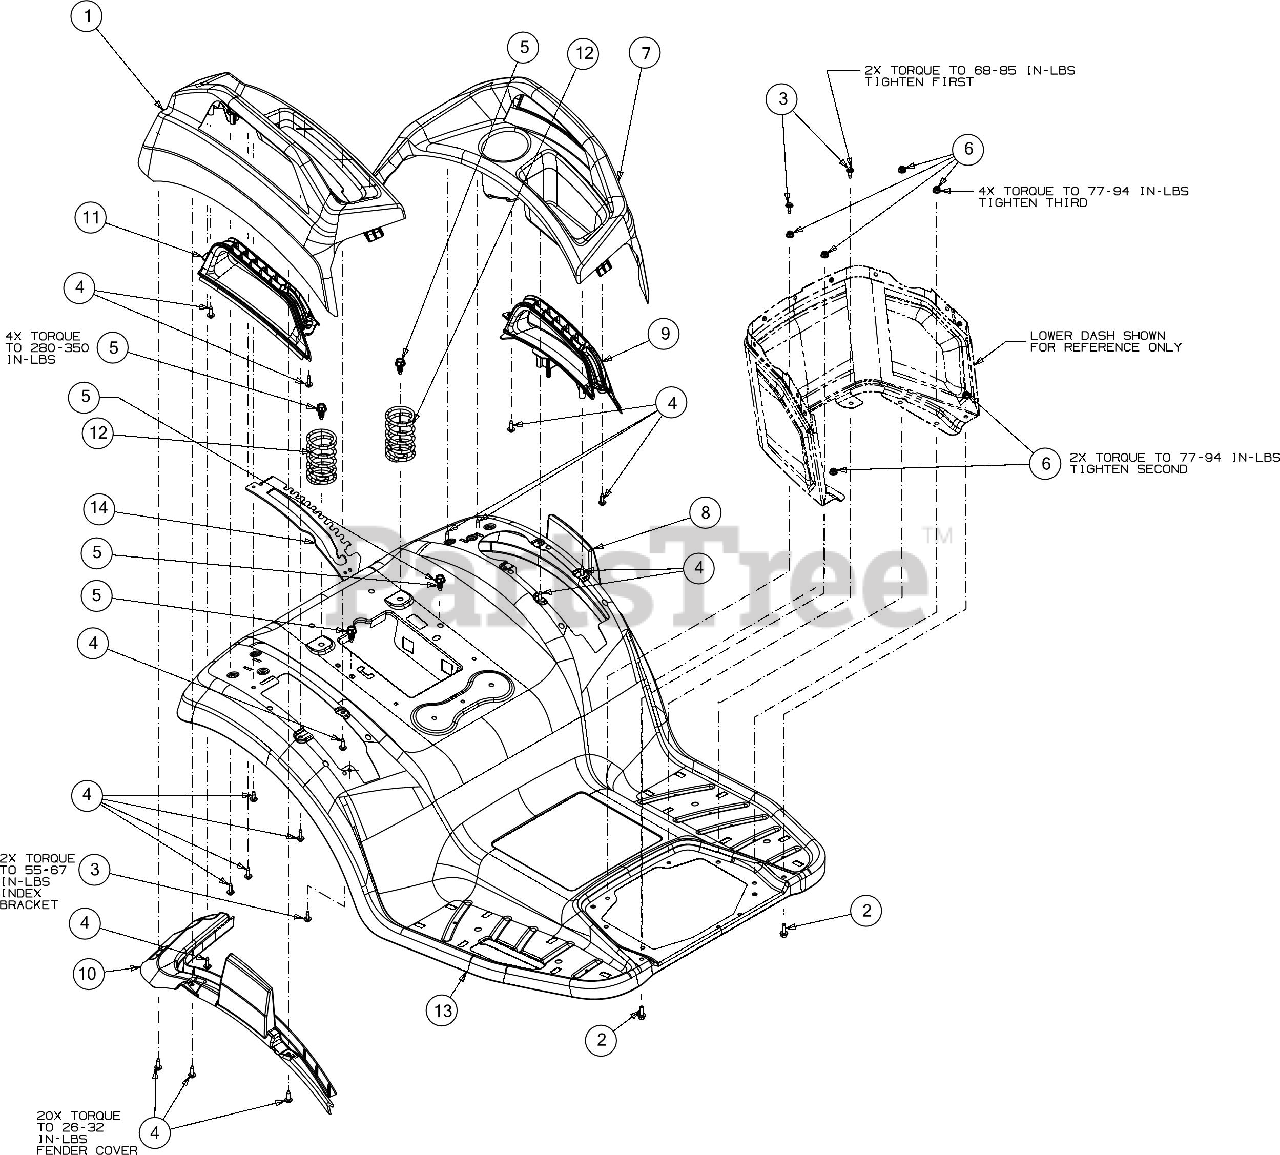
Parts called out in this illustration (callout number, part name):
1	UPPER FENDER COVER (RH)
2	SCREW 1/4-20 x .75 GR5
3	SCREW M6-1 x .625
4	SCREW 1/4-10 x .750
5	HEX SCREW WASH TT 3/8-16 x .875
6	FLANGE LOCK NUT
7	FENDER COVER (LH)
8	FENDER COVER (LH)
9	HANDLE COVER (LH)
10	FENDER COVER (RH)
11	HANDLE COVER (RH)
12	COMPRESSION SPRING 2.18 x 3.65 x .207
13	REAR FENDER
